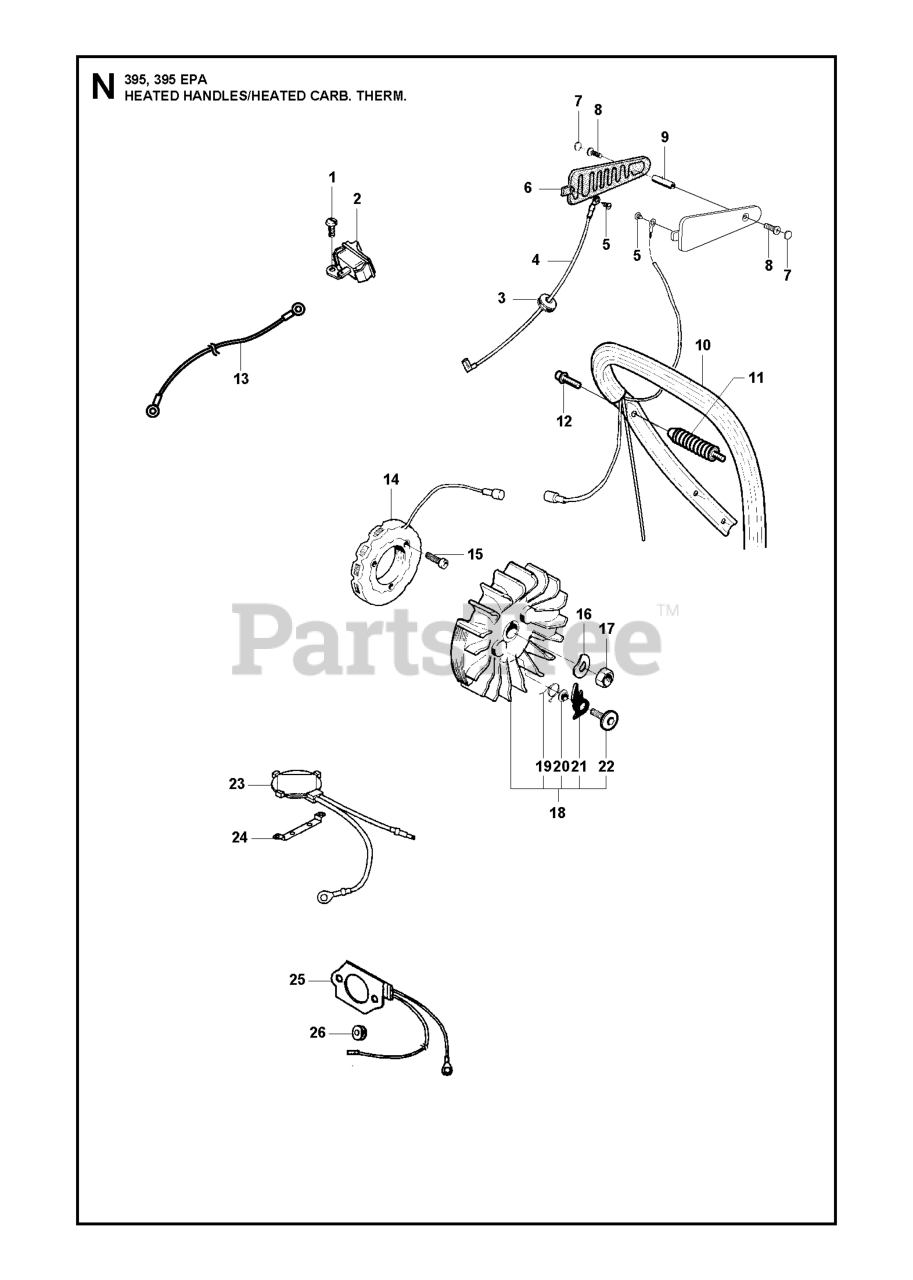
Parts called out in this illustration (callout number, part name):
8	SCREW 3X10
15	SCREW MC6S 4X12
16	WASHER 8.4X16
22	SCREW M5X14
23	THERMOSTAT
25	FOIL ELEMENT
